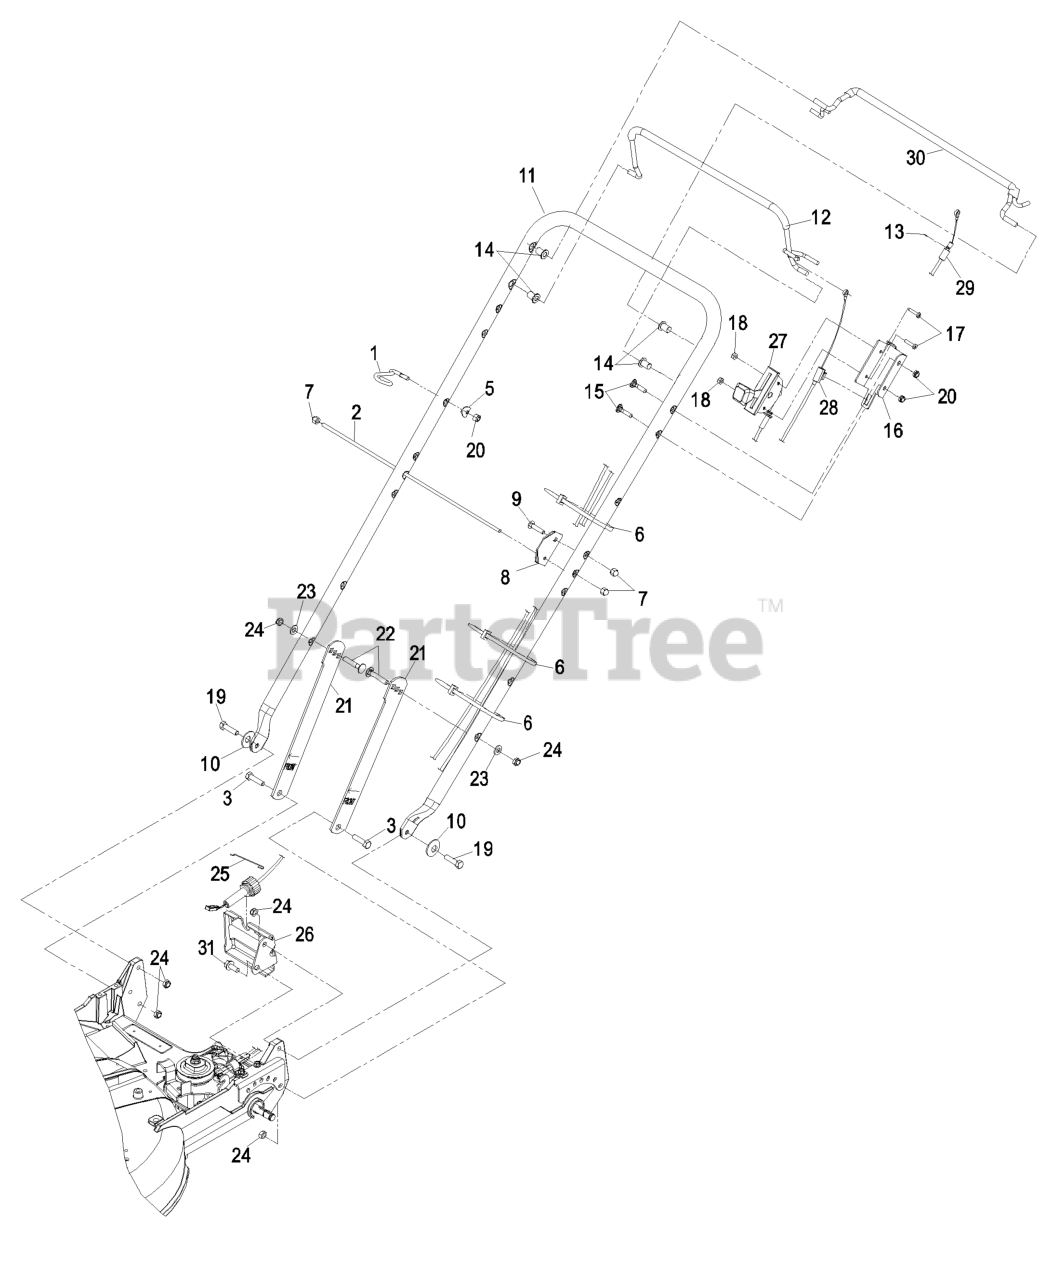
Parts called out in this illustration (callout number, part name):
1	GUIDE-ROPE
2	ROD, BAG SUPPORT
3	SCREW-HH
4	SCREW-HH
5	WASHER
6	TIE-CABLE
7	NUT-CAP
9	SCREW-CARR
10	WASHER-BELLEVILLE
11	HANDLE M21
14	BUSHING
15	BOLT-HANDLE
16	BRACKET, THROTTLE
17	SCREW-PPH
18	NUT-LOCK, NI
19	SCREW-HH
20	NUT-LOCK, NI
21	LATCH,HANDLE
22	BOLT-CARR
23	WASHER-PLAIN
24	NUT-LOCK, NI
25	RETAINER-CABLE
26	BRACKET-ADJUSTMENT, TRACT
27	CABLE,THROTTLE KAWASAKI
28	CABLE,BRAKE KAWASAKI
29	CABLE,TRACTION M21
30	ASM,TRACTION BAIL W/GRIP
31	Screw-HWH 5/16-18 X 3/4 Tf
